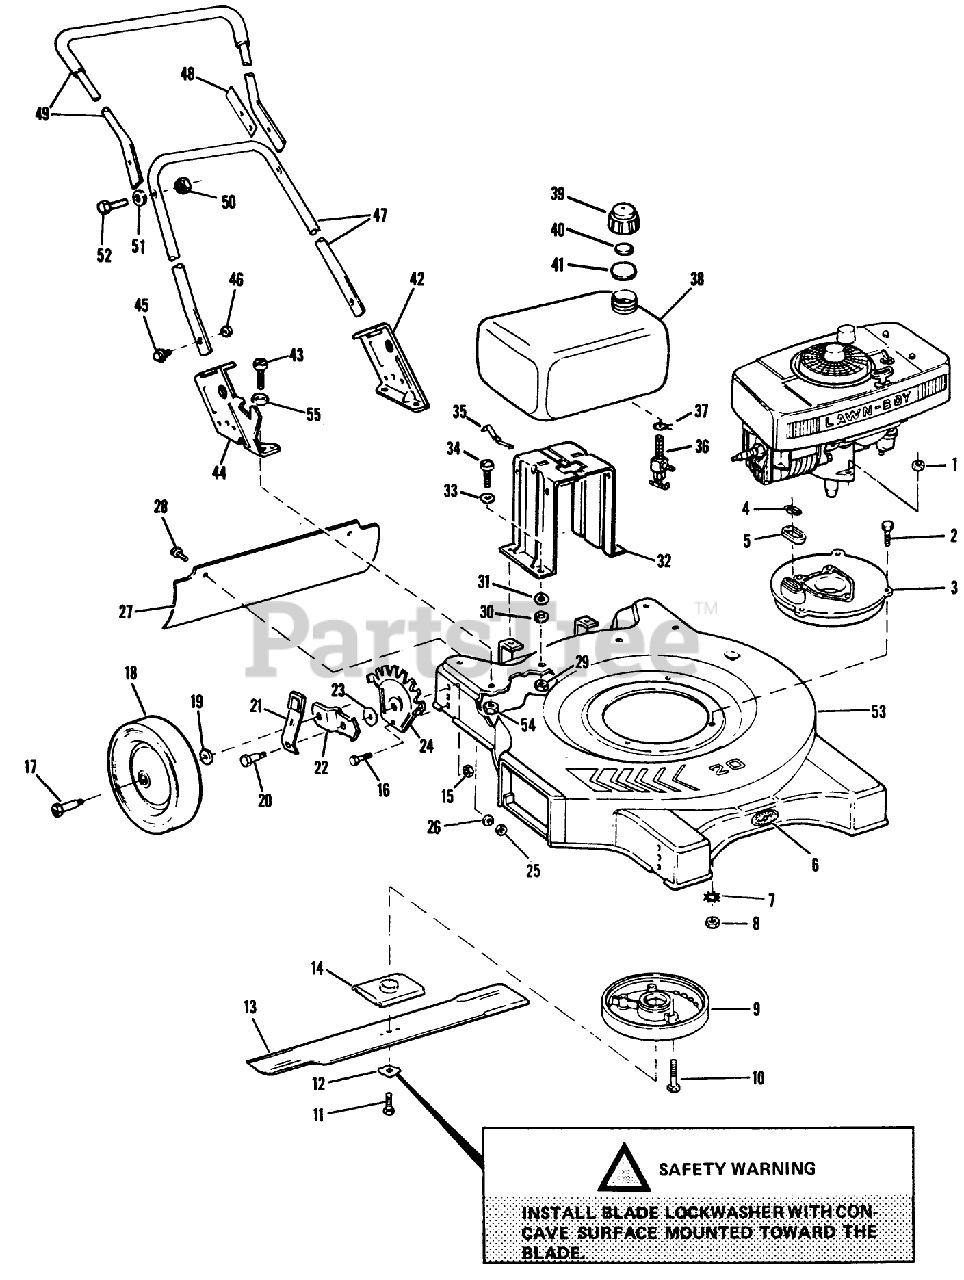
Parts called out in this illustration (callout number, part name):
1	NUT-LOCK F
3	Muffler-Top Half
5	GASKET S
7	Lockwasher
8	NUT-LOCK F
9	Muffler-Bottom Half
10	Bolt-Muffler
12	LOCKWASHER
13	Blade (20 inch)
15	LOCKNUT
17	BOLT-SHOULDER
19	WASHER WROUGHT
25	LOCKNUT E
29	LOCKNUT E
34	BOLT PIONEER
36	VALVE&SCREEN SM
37	CLAMP - HOSE S
40	GASKET S
41	BAFFLE - FOAM SM
46	NUT-JAM, LOCKING
47	Handle Bottom
49	Top Handle Grip Assy
50	LOCKNUT E
51	WASHER-CURVED
53	Housing Baffle
54	NUT-LOCK F
55	Cover-Spark Plug
